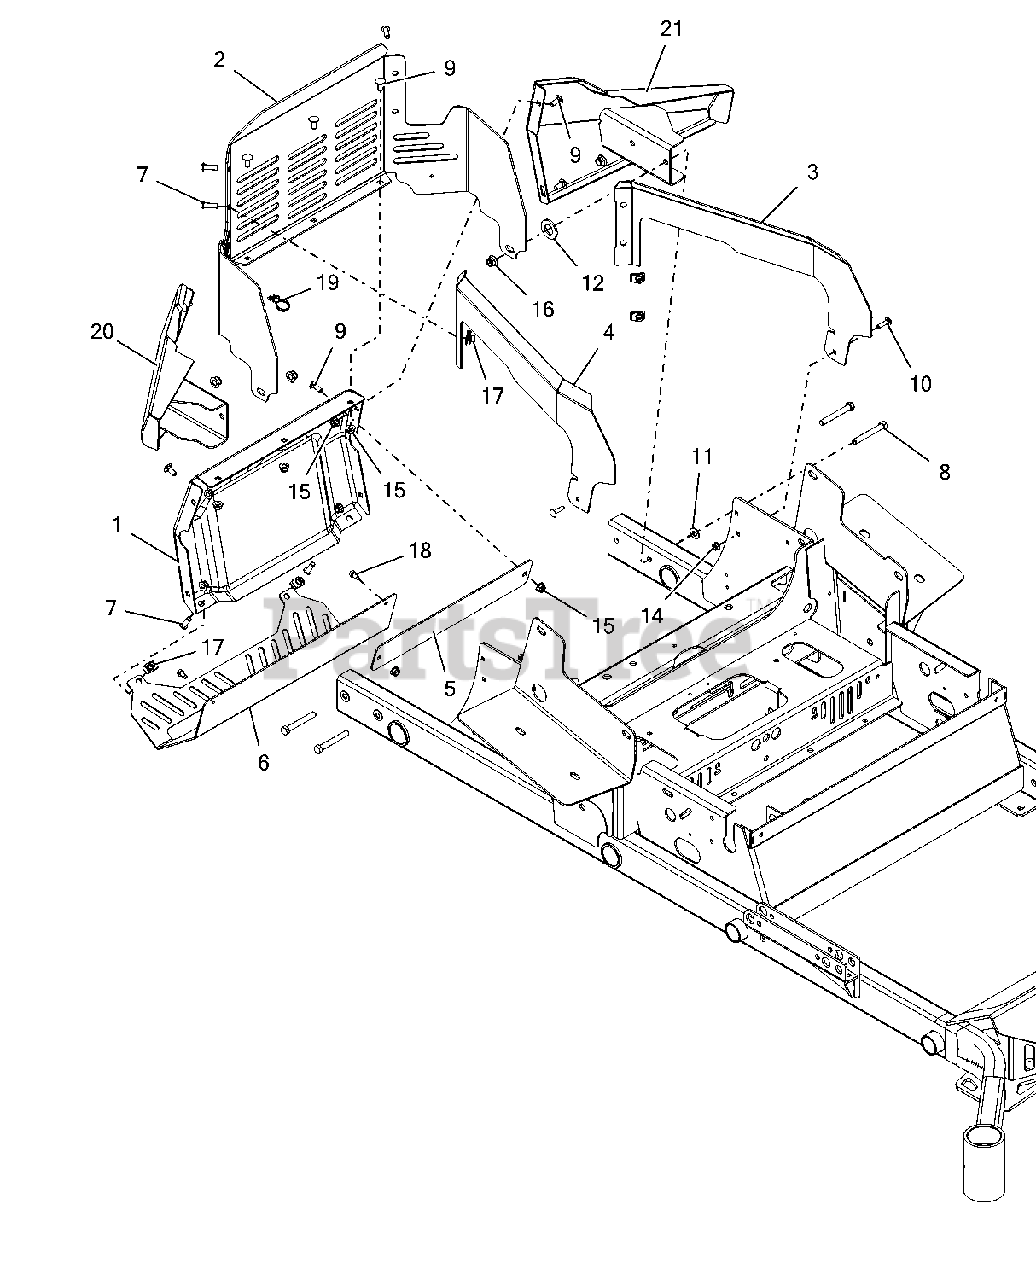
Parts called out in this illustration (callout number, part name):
1	BUMPER, PT200/400 REAR (BLACK)
2	GUARD, PT400 ENGINE (BLACK)
3	TRIM, HOOD STYLE (LEFT) (RED)
4	TRIM, HOOD STYLE (RIGHT) (RED)
5	PLATE, BACKER (RED)
6	GUARD, PT200/400 MUFFLER (BLACK)
7	SCR-SKH .31-18X1.00 BTNHD YWZC
8	BLT-HEX .38-16X2.75 GR5 YWZC
9	BLT-RDHDSQNK .31-18X.75 G5 YWZC
10	BLT-RDHDSQNK .25-20X1.00 G5 YWZC
11	WSHR-FL-STL.406X.812X.065 YWZ
12	WSHR-FL-STL.812X1.50X.135YWZC
14	NUT-LK-NYL-FLG .25-20 YWZC
15	NUT-LK-NYL-FLG .31-18 YWZC
16	NUT-LK-NYL-FLG .38-16 YWZC
17	NUT-CLIP RETAINER 5/16-18X.56
18	SCR-TAP .25-20X.50 HWH TR YWZ
19	CABLE TIE W/ TREE (.25 HOLE)
20	WLDMT, RIGHT REAR BUMPER WING (BLACK)
21	WLDMT, LEFT REAR BUMPER WING (BLACK)
